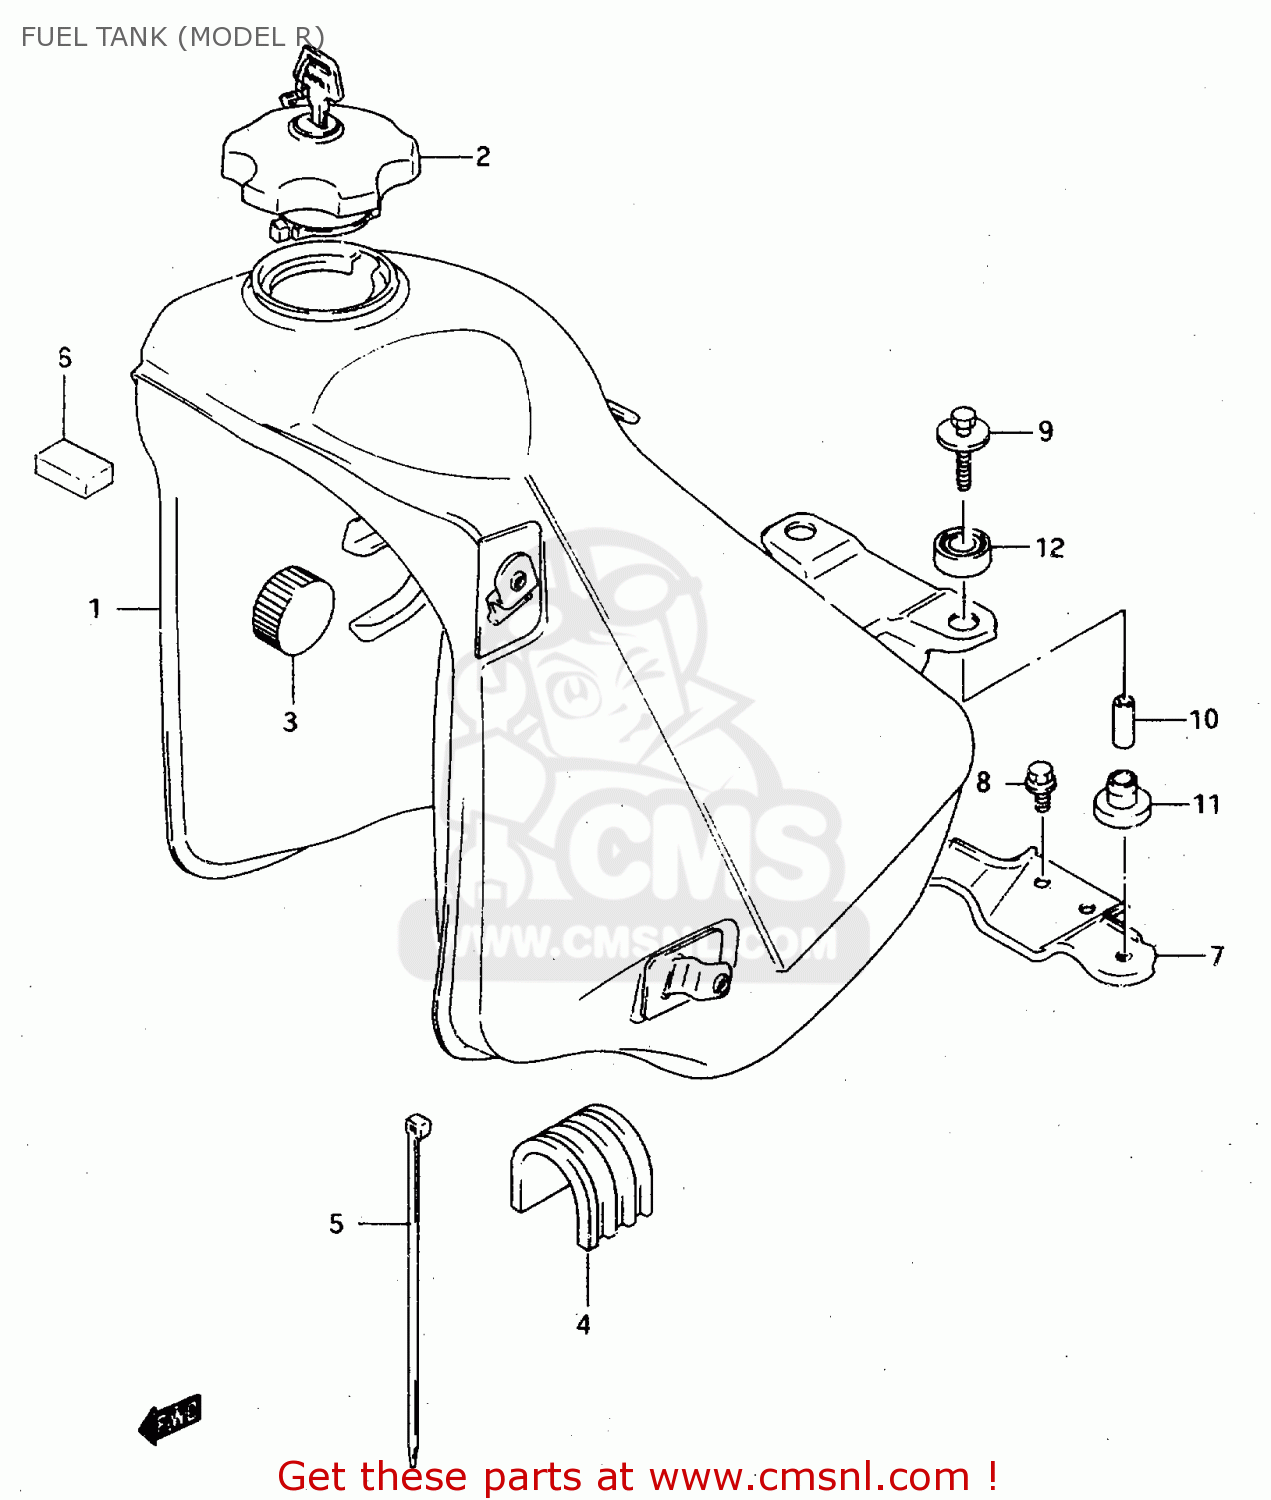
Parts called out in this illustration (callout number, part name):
1	TANK, FUEL (BLUE)
2	CAP SET,FUEL TANK
3	CUSHION
4	CUSHION,FUEL TANK FR UPR
5	CLAMP(L:250)
5A	CUSHION,FUEL TANK SIDE
6	BRACKET,FUEL TANK RR
7	BOLT
8	BOLT
9	BOLT
10	CUSHION
11	CUSHION
12	CUSHION
